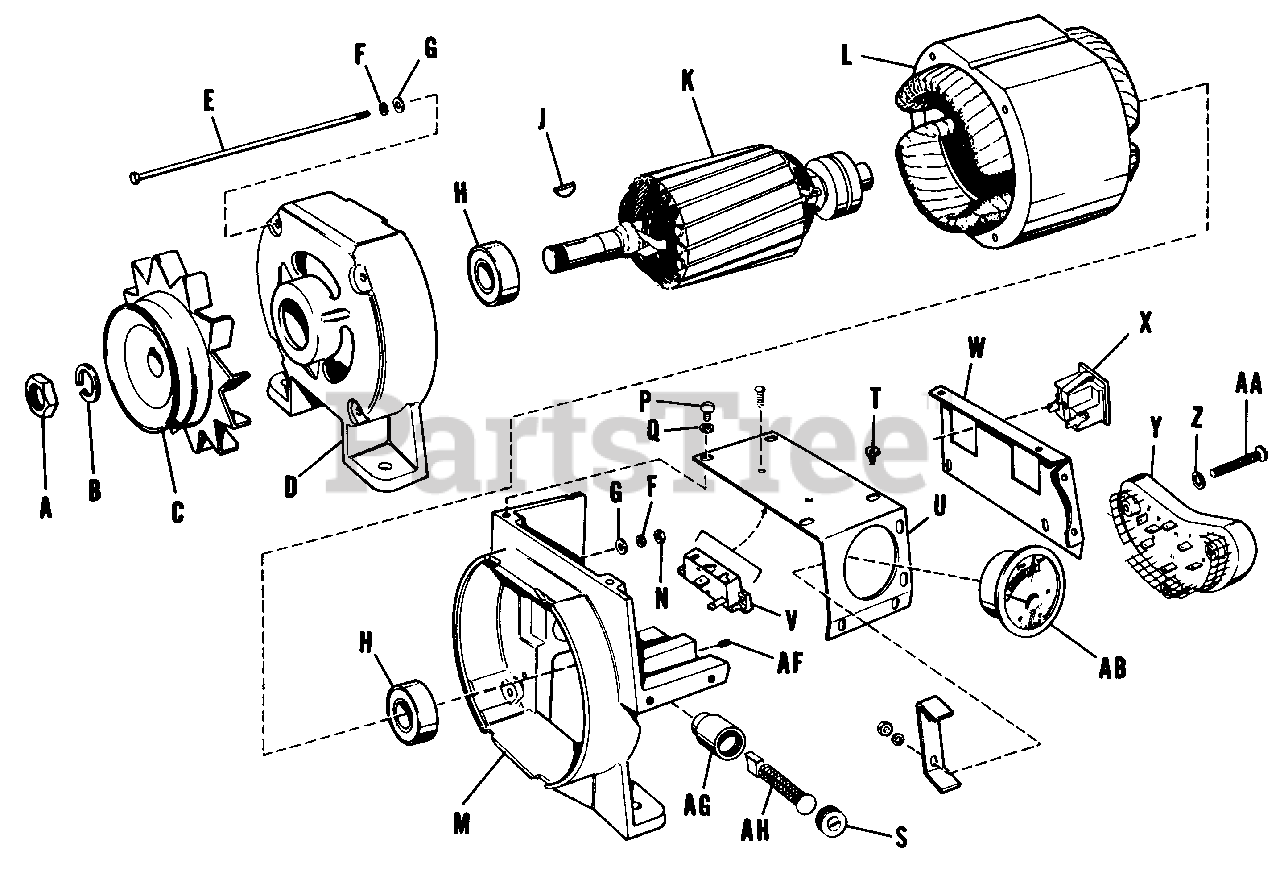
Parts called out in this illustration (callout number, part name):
B	Lockwasher
C	Fan and Pulley
D	Front Bearing Carrier
E	Hex Hd. Mach. Screw, 10-32 x 7 1/4" lg.
F	#10 Shakeproof Washer
G	#10 Flat Washer
J	#6 Woodruff Key
L	Field Assembly
M	Rear Bearing Carrier
N	10-32 Hex Nut
P	10-32 x 3/8" lg. Rd. Hd. Mach. Screw
Q	#10 Shakeproof Washer
S	Brush Holder Cap
T	#8 Pan Hd. Self Tapping Screw, 3/8" lg.
U	Brush Box Cover (Top)
V	Circuit Breaker Reset
W	Brush Box Cover (Back)
X	115 Volt Outlet
Y	Rectifier Pad Assy.
Z	1/4" Shakeproof Washer
AA	Rd. Hd. Cap Screw, 1/4"-20 x 1 3/4" lg.
AB	Voltmeter Assy.
AF	Allen Hd. Set Screw, 10-32 x 1/4" lg.
AG	Brush Holder
